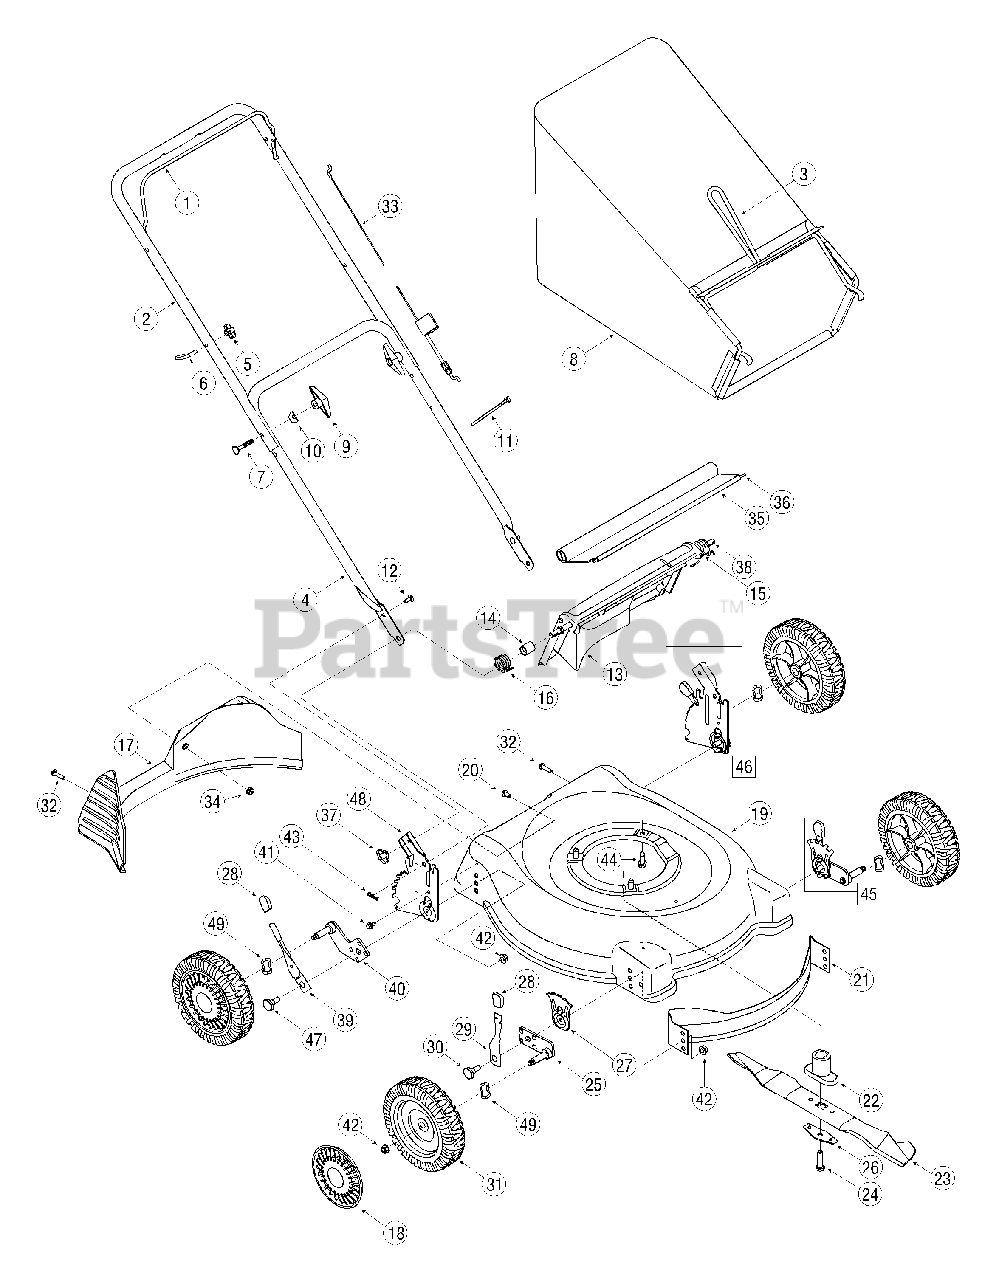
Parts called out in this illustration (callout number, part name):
5	Wing Nut
6	Rope Guide
7	Carriage Bolt, 5/16-18 x 2
8	Grass Bag Assembly
9	Hand Knob
10	Saddle Washer
11	Cable Tie
12	Carriage Bolt, 1/4-20
13	Rear Discharge Door
14	Spacer
15	Torsion Spring - LH
16	Torsion Spring - RH
17	Rear Baffle
18	Hubcap
21	Front Baffle
22	Blade Adapter
23	Mulching Blade
24	Hex Bolt, 3/8-24 x 1.5
25	Pivot Arm Assembly RH (8" wheel)
25	Pivot Arm Assembly LH (8" wheel)
26	Blade Bell Support
27	Front Adjustment Plate
28	Adjustment Lever Knob
29	Spring Lever Assembly
30	Shoulder Screw
31	Front Wheel 8 x 2.125 Zag BB Black
32	Screw, 1/4-15 x 1.250
33	Control Cable - 40"
34	Flange Lock Nut, 1/4-20
35	Trailshield
36	Trailshield Wire
37	Wing Nut, 1/4-20
38	Rear Door Pivot Rod
39	Spring Lever
40	Pivot Arm Assembly - RH
40	Pivot Arm Assembly - LH
41	AB Screw
42	Flange Lock Nut, 3/8-16
43	Hairpin Clip
44	TT Sems Screw, 3/8-16 x 1.0
45	Ht. Adj. Assy. Front - RH (8" wheel)
45	Ht. Adj. Assy. Front - LH (8" wheel)
46	Rear Handle Bracket Assy. - LH
46	Rear Handle Bracket Assy. - RH
47	Shoulder Screw
48	Handle Bracket, use ref # 46
49	Wave Washer .510 X .750 X .017
